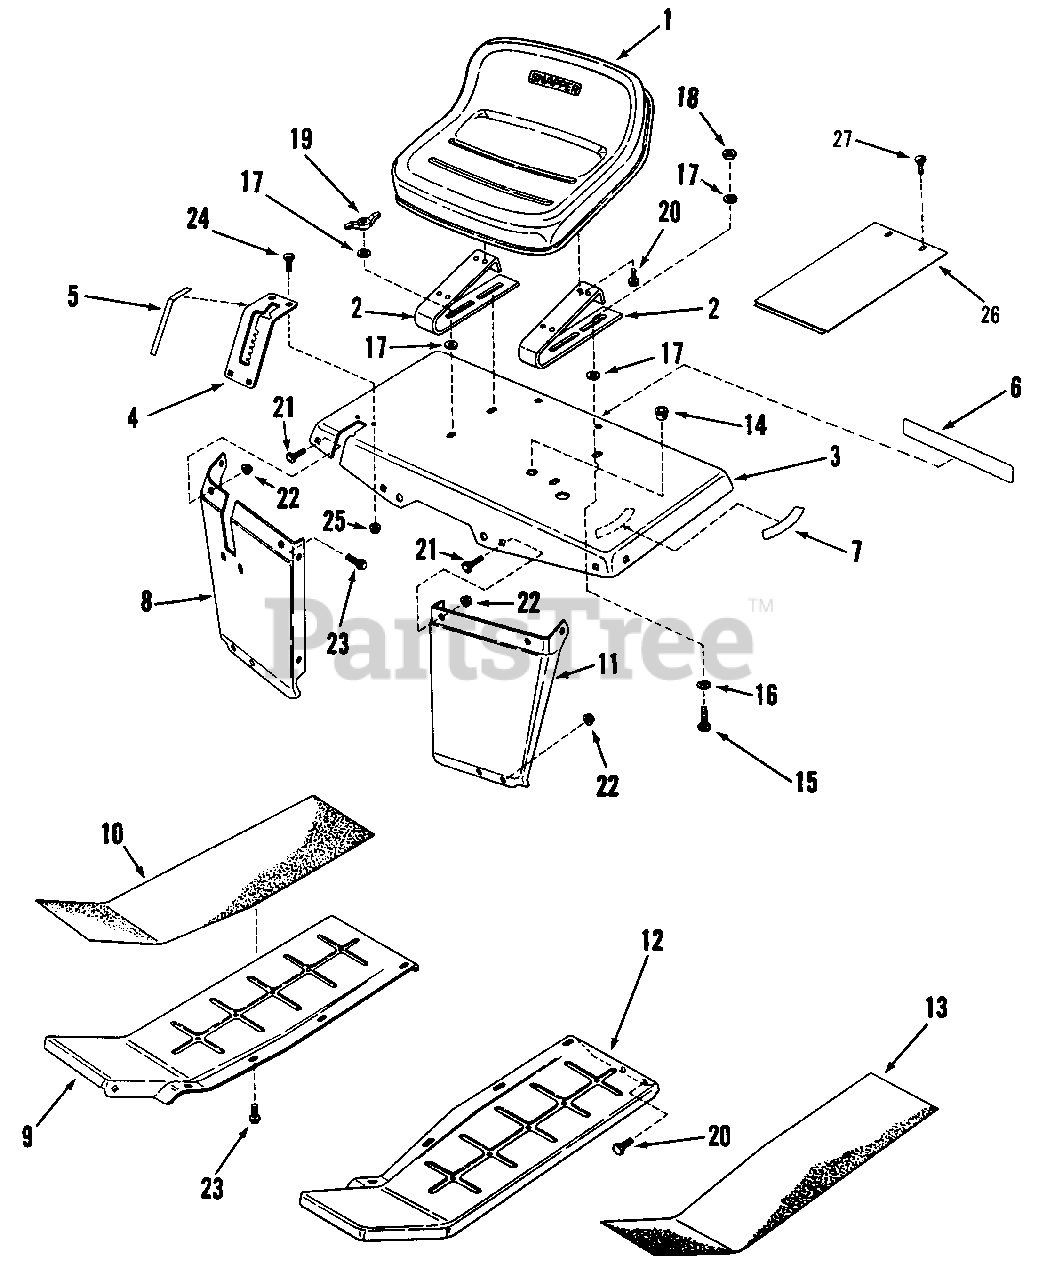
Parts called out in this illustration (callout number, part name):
1	SEAT, Operator's
2	SPRING, Seat
3	FENDER, Rear
3	FENDER, Rear w/access hole
4	DETENT, Shift
5	DECAL, Speed Shift
6	DECAL, SNAPPER
7	DECAL, HI-LOW RANGE (Shift)
8	EXTENSION, Right Side Fender
9	PANEL, Right Side Step
10	TREAD, Right Side (Non-Skid)
11	EXTENSION, Left Side Fender
12	PANEL, Left Side Step
13	TREAD, Left Side (Non-Skid)
14	RELIEF, Strain
15	BOLT, 5/16-18 x 1" Square Neck Carriage
16	RETAINER, 5/16 Bolt
17	WASHER, 5/16" x 1-1/4" x 3/32" Flat
18	NUT, 5/16-18 Hex Center Lock, Grade B or 5
19	WING-NUT, 5/16-18
20	BOLT, 5/16-18 x 1/2" Hex Flange Lock, Grade 5
21	BOLT, 5/16-18 x 1/2" Short Neck Carriage, Grade 5
22	NUT, 5/16-18 Hex Flange Lock, Grade 5
23	SCREW, 5/16-18 x 5/8" Self-Tap (14)
24	BOLT, 1/4-20 x 1/2" Short Neck Carriage, Grade 5
25	NUT, 1/4-20 Hex Flange Lock
26	COVER, Access
27	SCREW, 5/16-18 x 1/2" Hex Washer Self-Tap
